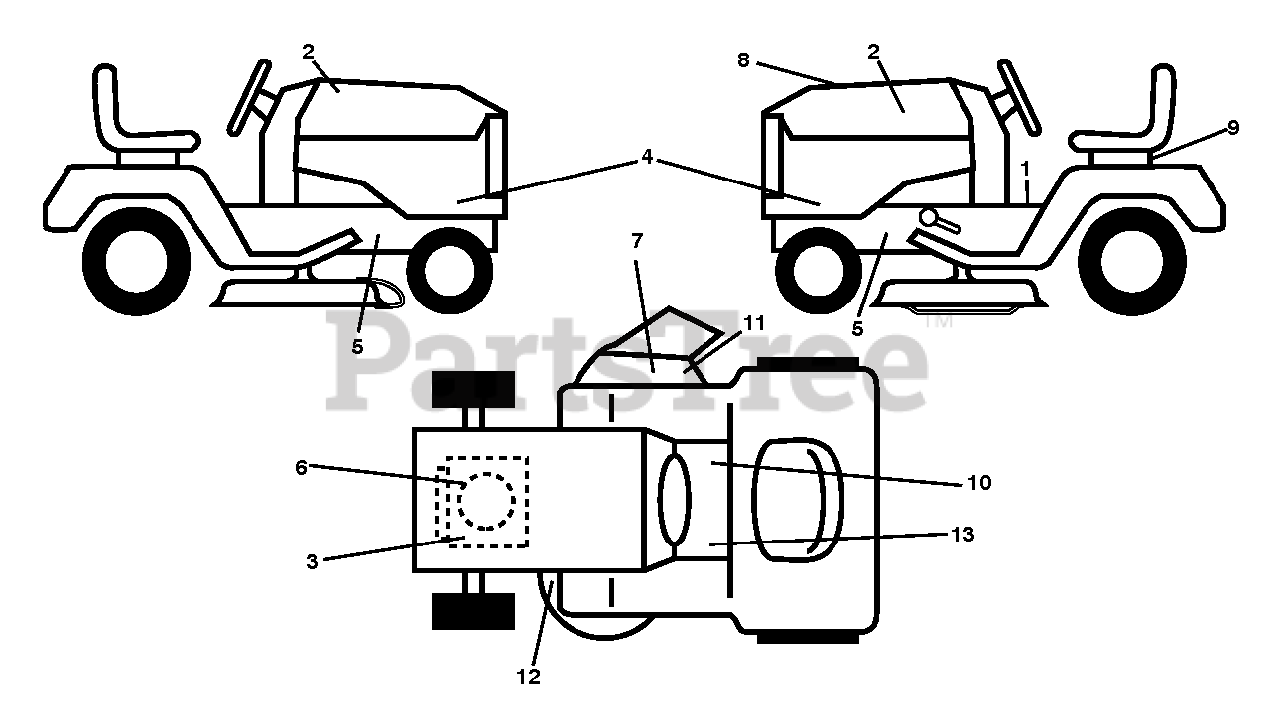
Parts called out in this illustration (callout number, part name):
1	DECAL.READ.OWN.MAN.SYMBOL.LT
2	DECAL.BADGE.170MM.TEXTLOGO.
3	DECAL.ENGINE.WARNING
5	DECAL.CHASSIS.HOT.MUFFLER
6	DECAL.ENG.BS.SER4155.RS.382023
7	DECAL.CUTFINGER.CE.02
8	DCL.RPL.BSM31.INTK.TLW.38.PMST
9	DECAL BTRY SYMBOLS
10	DECAL.PARKING.BRAKE.SADDLE.LT
11	DECAL.DFLCTR.WARNNG.CTFNGR.SYM
12	DECAL.DECK.SCH.36,38,94.NONCR
13	DECAL.FNDR.SDLE.BRAKE.CLUTCH.6
